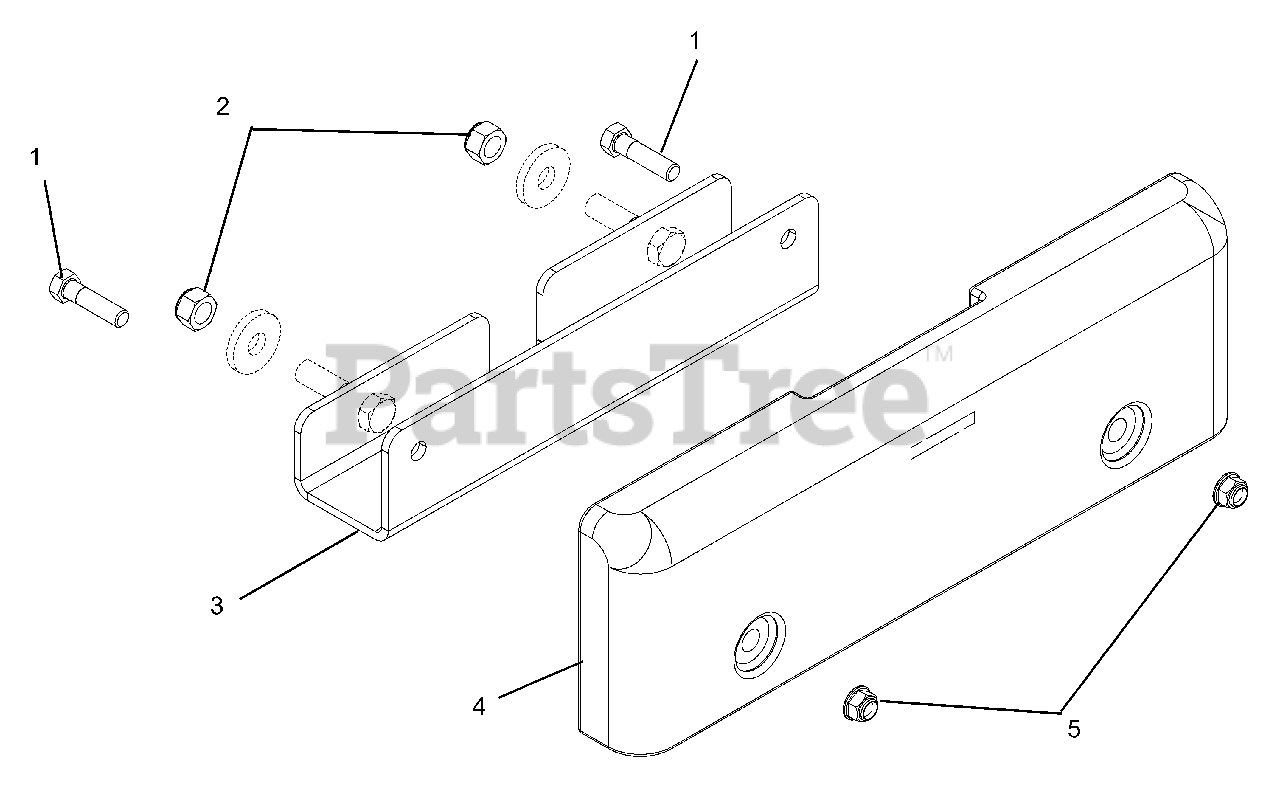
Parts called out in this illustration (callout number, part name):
1	@BLT-HEX .50-13X2.75 GR5 YWZC
2	@NUT-LK-NYL-FLG .63-11 YWZC
3	BKRT, ZOOM BAGGER WGT
4	WEIGHT, CAST IRON
5	@NUT-LK-NYL-FLG .50-13 YWZC
